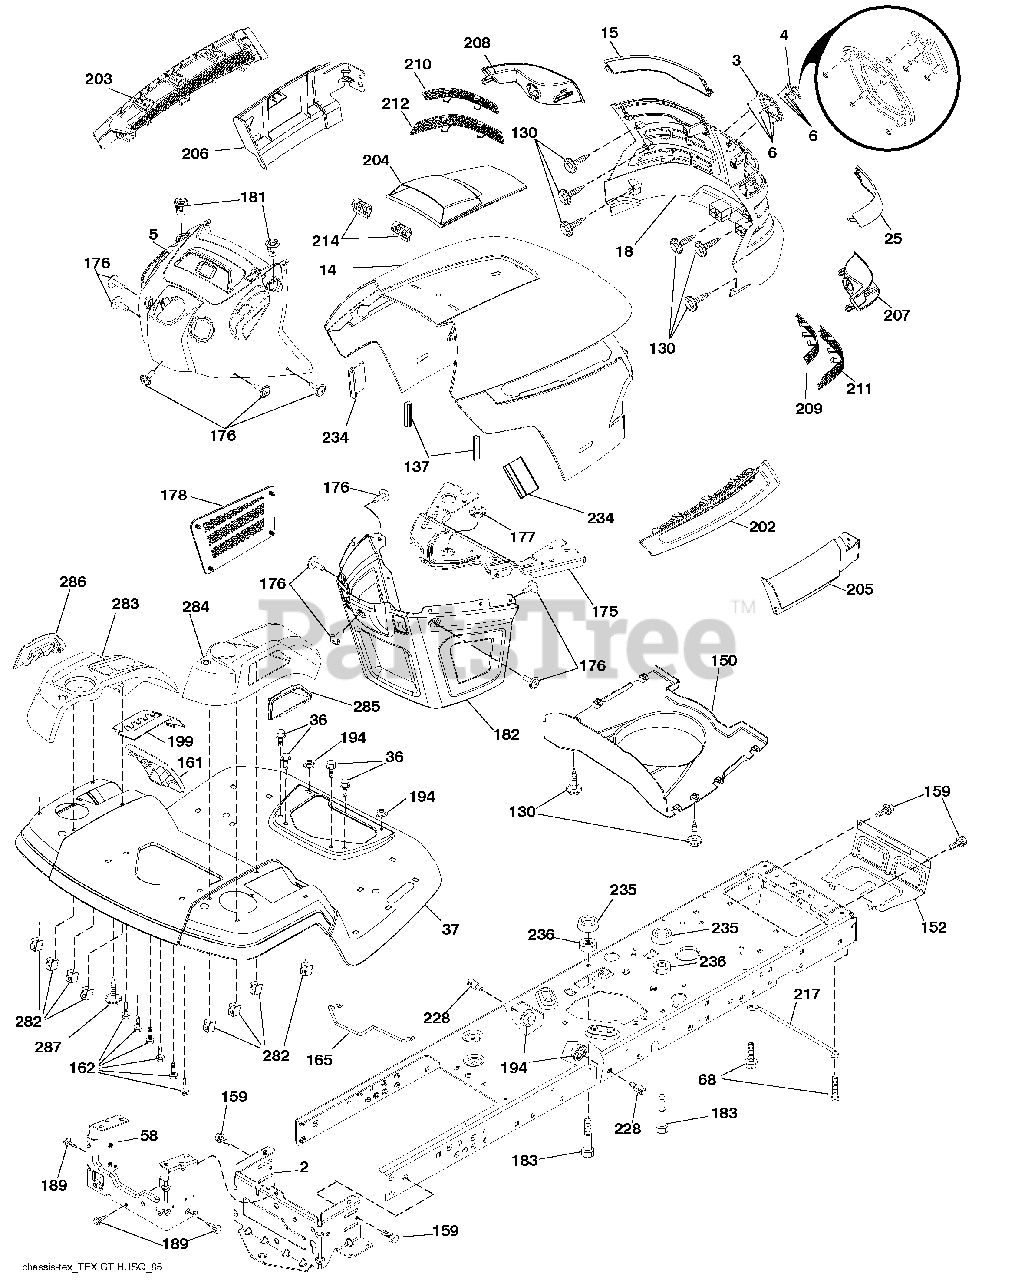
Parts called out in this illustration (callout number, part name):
3	Trim, Husq.
4	Logo
5	Dash
14	Hood
18	Grille/Lens Asm.
36	Screw 5/16-18 x 3/4
58	Drawbar Upper
68	Screw Thdrol 5/16-18 x 1/2
130	Screw 10 x 0.750 BOS Thread
137	Bumper Dash
152	Shield Browning
159	Screw 3/8-16 x 3/4
161	Window Fuel
162	Screw Hex Wsh Hi-Lo 1/4 x 1/2 unc
165	Support Tank Rear
175	Crossmember
176	Screw 10-24 x 5/8
177	Bushing Steering
178	Cargo Net Asm.
180	Chassis
181	Bushing Mtg. Fender Crgo
182	Dash Lower
183	Bolt 5/16-18 x 1-1/4
189	Screw 5/16-18 x 3/4
194	Nut Lock Hex Flange 5/16-18
199	Plate Deck Lift
202	Vent Side Hood RH
203	Vent Side Hood LH
204	Vent Top Hood
205	Skirt Hood Side RH
206	Skirt Hood Side LH
209	Insert Hex Top RH
210	Insert Hex Top LH
211	Insert Hex Bottom RH
212	Insert Hex Bottom LH
214	Clip Retainer Tinner
228	Stud Fastener
234	Bumper Hood
235	Spacer Fender
236	Nut Lock 5/16-18 unc
282	Clip Retainer Console
283	Console Deck Lift
284	Console Shift
285	Console Insert RH
286	Console Insert LH
287	Screw 1/4-20 X 3/8
